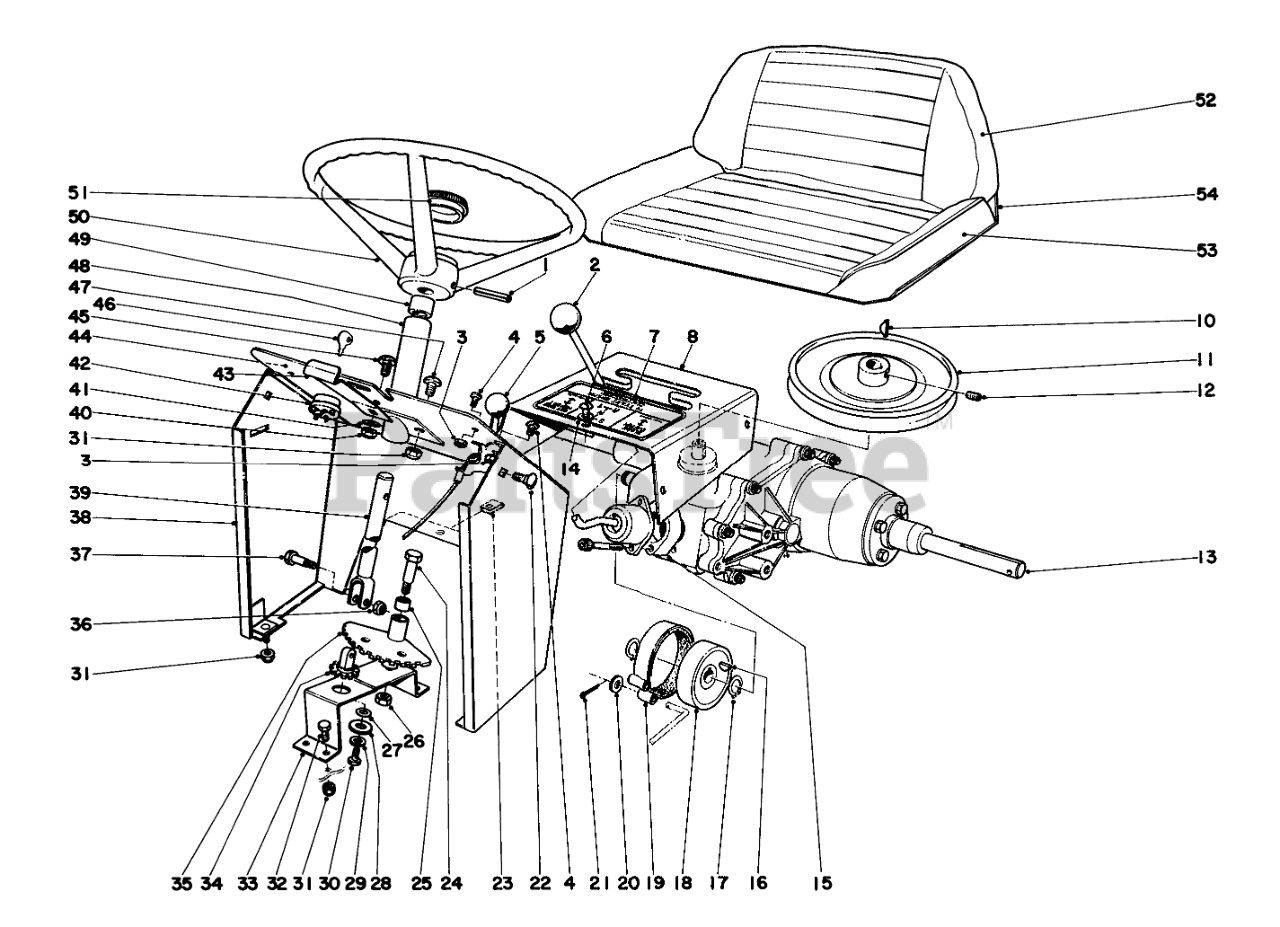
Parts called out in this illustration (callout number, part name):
1	PIN-ROLL
3	NUT-KEPS
5	Throttle Control
6	SCREW
7	Decal-Shift Pattern
8	Tunnel
10	KEY-WOODRUFF
11	Pulley
12	Set Screw
13	Transaxle
14	WASHER-LOCK
15	Extension Shift Housing
16	KEY-WOODRUFF
17	RING-SNAP, EXTERNAL
18	Brake Drum
19	Brake Band
20	WASHER-FLAT
21	PIN-COTTER
22	BOLT-CARR
23	SPEED NUT
24	Shoulder Bolt
25	BUSHING
26	Nut
27	Spacer
28	Washer
29	WASHER-LOCK
30	SCREW-HH
31	NUT-LOCK, CONE
32	SCREW-HH
33	Bracket
34	Pinion Steering
35	Gear Steering
36	NUT-HEX
37	Screw Shoulder
39	Steering Shaft
40	NUT-LOCK, CONE
41	WASHER-FLAT
42	STARTER SWITCH
43	Hood Latch
44	Decal Dash
45	Carriage Bolt
46	Key
47	Round Head Screw
48	Steering Tube
49	BUSHING
50	Steering Wheel
51	Steering Wheel Cap
52	Seat Back
53	Seat Cushion
54	Frame-Seat
